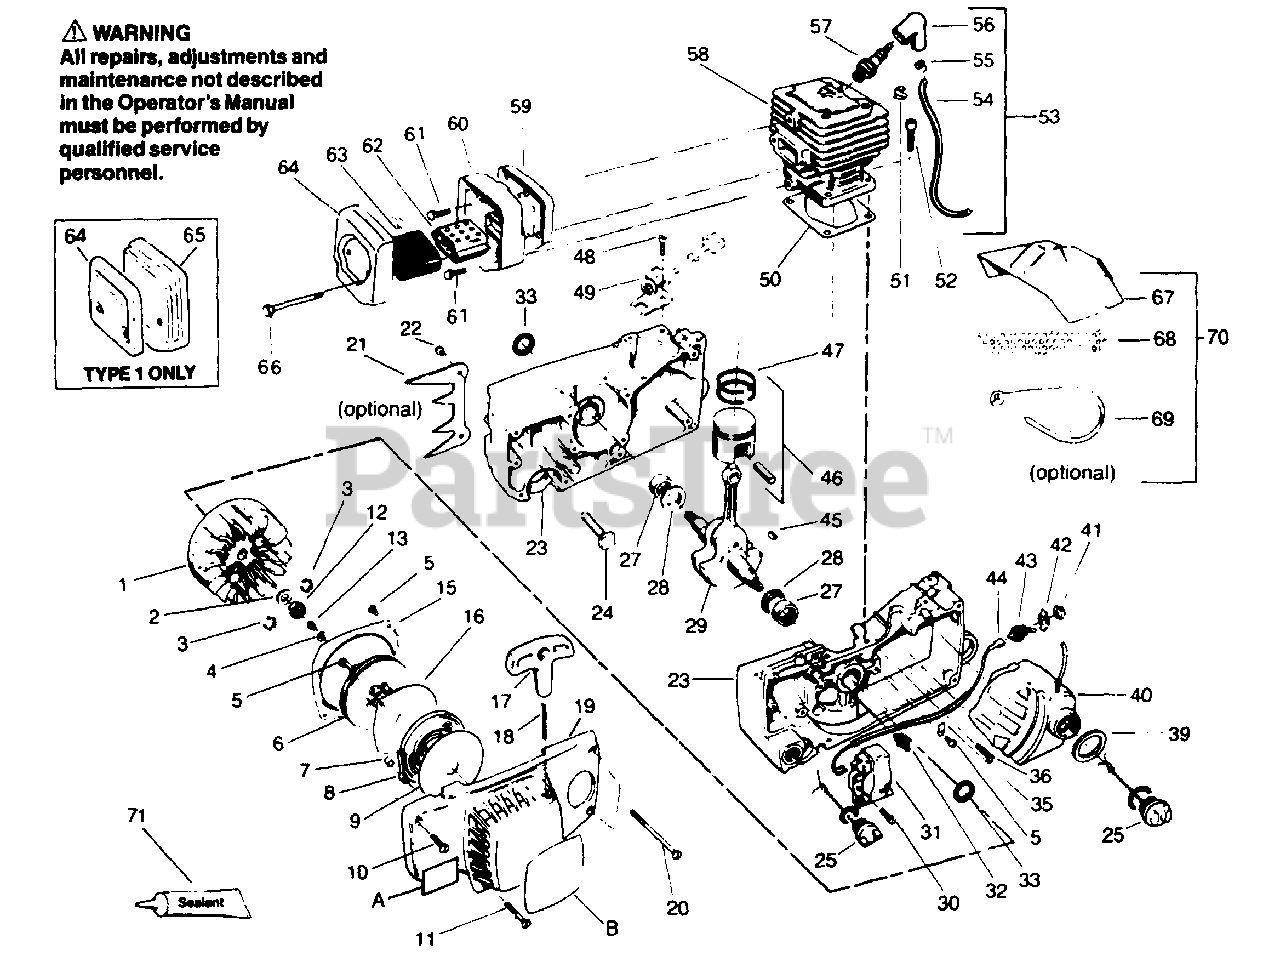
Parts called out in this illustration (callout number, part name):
1	Flywheel Ass'y.
2	Washer - Flywheel
3	Spring - Starter Dog
4	Washer - Starter Pulley
5	Screw - 32 x 5/16 - Hex Hd. - Disc. Mounting
6	Pulley Starter
7	Bushing Recoil Spring
8	Spring - Starter Recoil
9	Disc. Recoil Spring - Outer
10	Screw - 10 - 24 x 1 - Oval Hd. Fan Housing - (Top Front)
11	Screw - 10 - 24 x 1 - 3/8 - Fan Housing (Lower Front)
12	Flywheel Nut 3/8 - 24
13	Screw - 10 - 24 x 1/2 - Starter Pulley
15	Air Baffle
16	Disc. Recoil Spring - Inner
17	Handle Starter Rope
18	Rope Kit
19	Fan Housing Assembly
20	Screw - 10 - 24 x 9/64 - Fan Housing (Rear)
21	Spur
22	Screw - 10 - 24 x 9/16 - Hex Hd. - Spur
23	Crankcase Ass'y.
24	Kit - Bar Stud Replacement (5/16")
25	Kit - Oil & Fuel Cap
27	Bearing - Crankshaft
28	Thrust Washer - Crankshaft
29	Crankshaft Ass'y.
30	Screw - 10 - 24 x 12 - Module Mnt.
31	Ignition Module
32	Clamp - High Tension Lead - Crankcase
33	Seal - Crankshaft
35	Clamp - Module Lead
36	Screw - 10 - 24 x 11/16 - Fil. Hd. Crankcase
39	Seal - Fuel Tank Neck
40	Fuel Tank Assembly
41	Nut - Switch Mounting
42	Plate - Ignition Switch
43	Switch - Toggle
44	Leadwire - Switch
44	Serial #35474496 and after
44	Before Serial #35474495
45	Key - Flywheel
46	Piston Assembly
47	Rings - Piston
48	Screw - 10 - 24 x 3/8 Fil. Hd. Choke Bracket
49	Bracket & Bushing Assembly - Choke
50	Cylinder Gasket
51	Clip -High Tension Lead Cylinder
52	Cylinder Screw - 1/4 - 20 x 7/8
53	High Tension Lead Assembly
54	High Tension Lead
55	Connector - Spark Plug
56	Boot - Spark Plug
57	Spark Plug
58	Cylinder
59	Back Plate - Muffler
60	Muffler Body
61	Screw - 1/2 - 24 x 1/2 - Hex Hd. Muffler Body to Cylinder
62	Diffuser - Muffler
63	Screen - Spark Arrestor
64	Muffler Cover
65	Shield Muffler - Type I Only
66	Screw - 1/4 - 20 x 2 - 1/2 - Hex Cap - Muffler Cover
67	Cover Carburetor - With Rear Vent
68	Screen - Winter
69	Tie Strap
70	Winter Kit
71	Sealant - Crankcase
A	Decal - Professional User Bow Guide Powerhead only
B	Decal - Fan Housing
